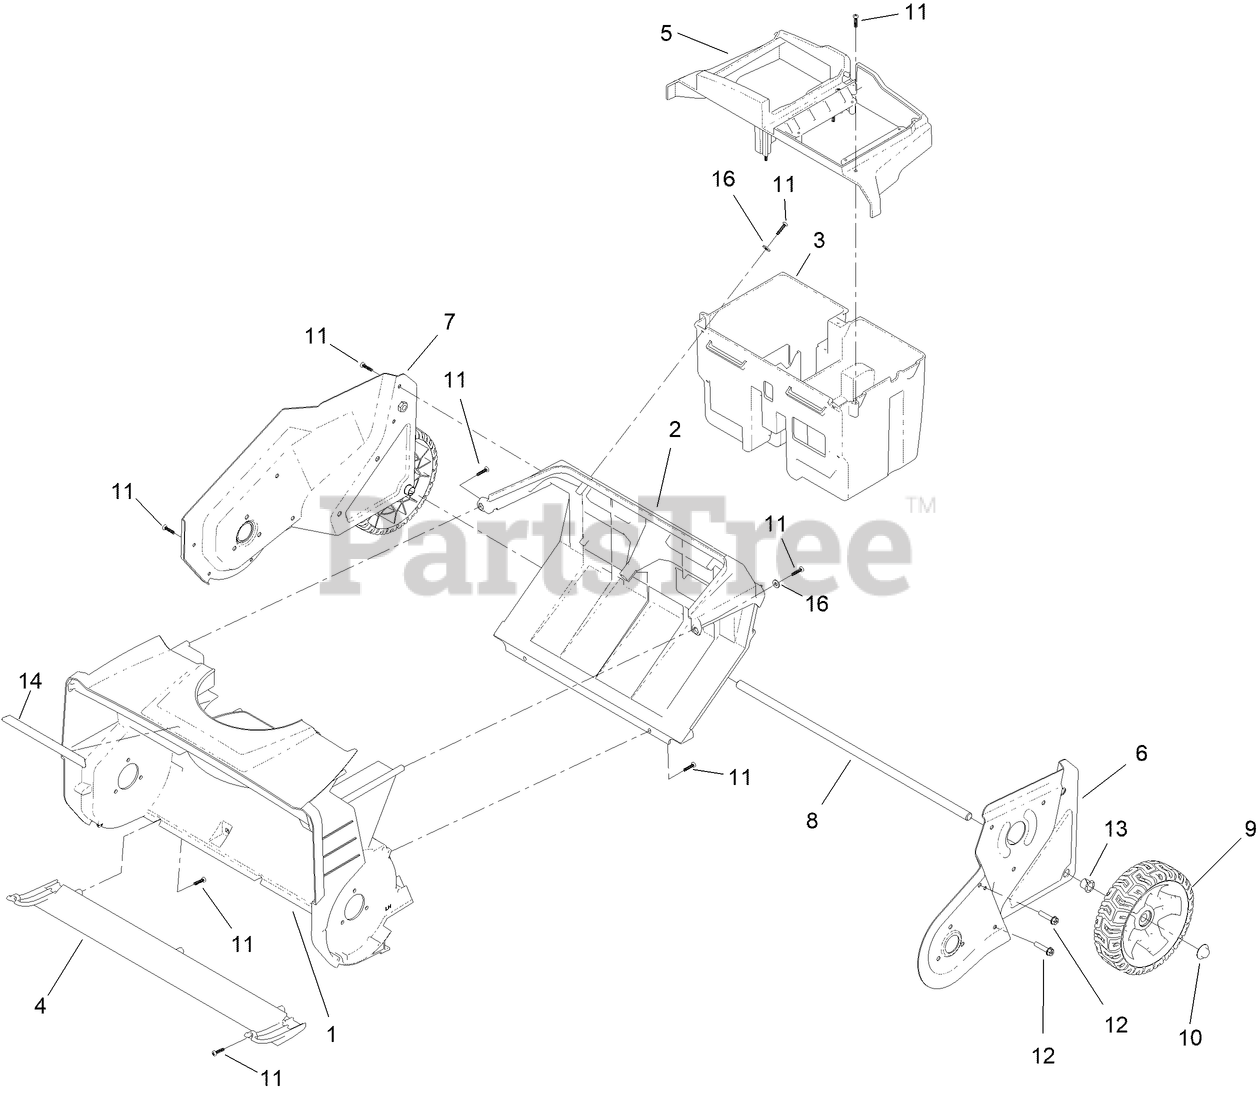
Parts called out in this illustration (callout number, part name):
1	HOUSING
2	BULKHEAD
3	CONTAINER-BATTERY
4	SCRAPER
5	SKIRT-CONTAINER, BATTERY
6	PLATE-FRAME ASSEMBLY, LH
7	PLATE-FRAME ASSEMBLY, RH
9	WHEEL ASM
10	NUT-PUSH
11	SCREW-PPH
12	SCREW-PLASTIC,HWH
13	BUSHING-NYLINER
14	DECAL-POWER EDGE
16	WASHER-PLAIN
